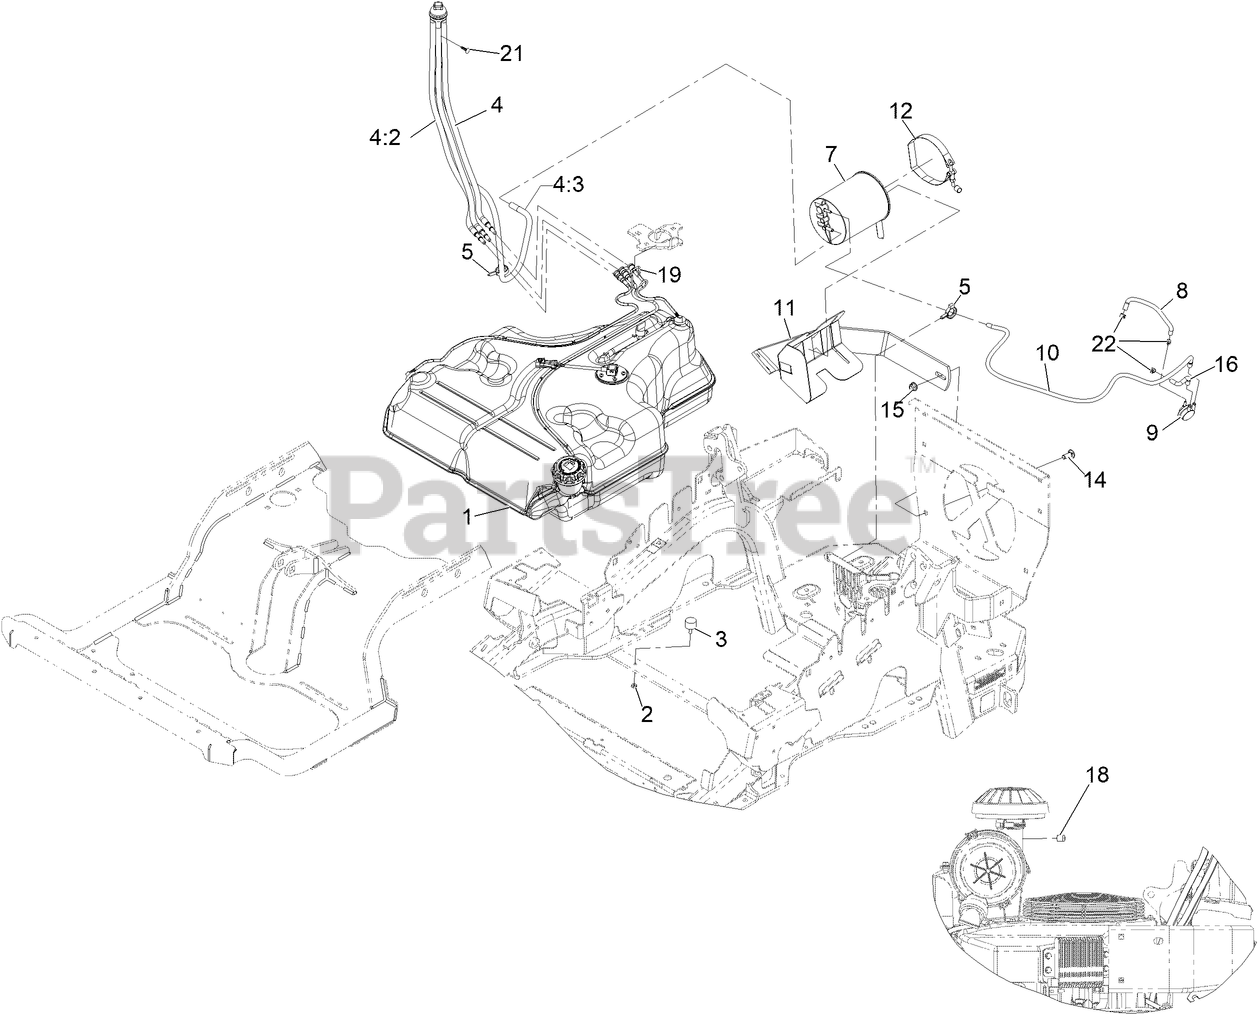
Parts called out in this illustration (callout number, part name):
1	FUEL TANK ASM
2	NUT-JAM
4	FUEL MANIFOLD VENT ASM
4:2	HOSE-FUEL
4:3	HOSE-FUEL
5	CLAMP-HOSE
7	CANISTER-CARBON, 1200CC
8	HOSE-VENT,FORMED
9	VALVE-CONTROL, VACUUM
10	HOSE,VENT,FORMED
11	MOUNT-CANISTER
12	CLAMP, T-BOLT
14	SCREW-CARR
15	NUT-HF, NI
16	HOSE-VENT, FORMED
18	PLUG-PORT
19	RETAINER-LINE, VAPOR
21	PLUG-PLASTIC
22	Clamp - Hose
